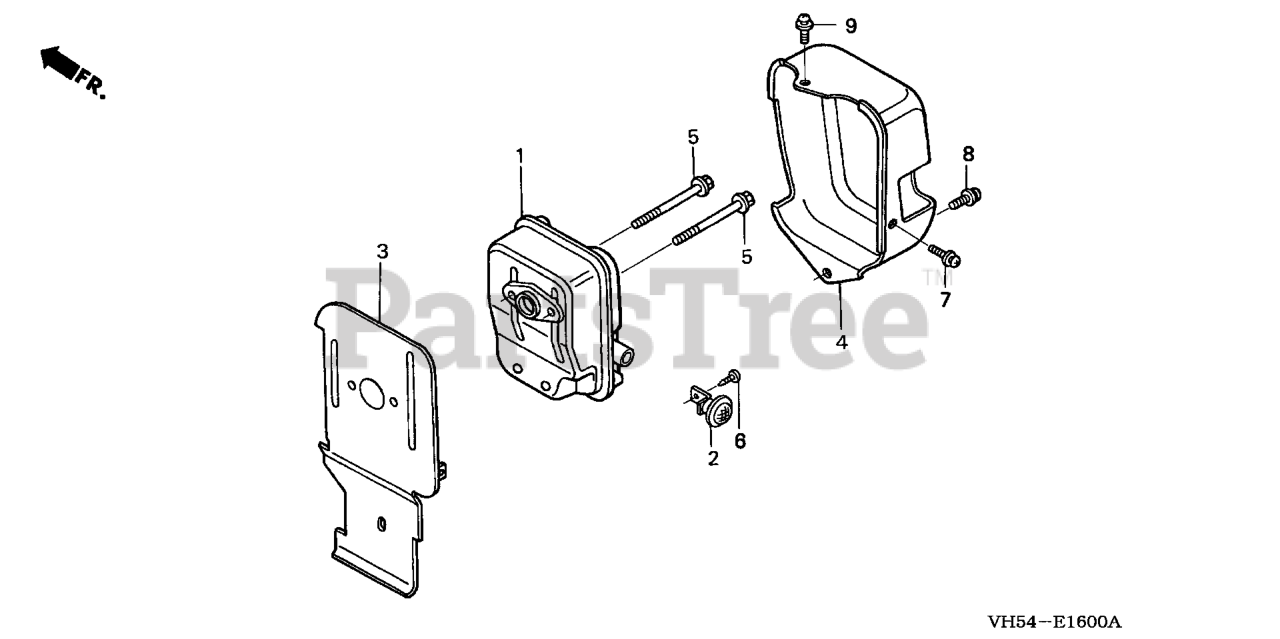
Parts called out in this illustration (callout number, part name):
1	MUFFLER
2	ARRESTER, SPARK
3	GUIDE, AIR EX.
4	COVER, TOP (INNER)
5	BOLT, FLANGE (5X50)
6	SCREW, TAPPING (4X6) (TO INSTALL OPTIONAL SPARK ARRESTER)
7	SCREW-WASHER (5X8)
8	SCREW-WASHER (5X10)
9	SCREW-WASHER (5X16)
